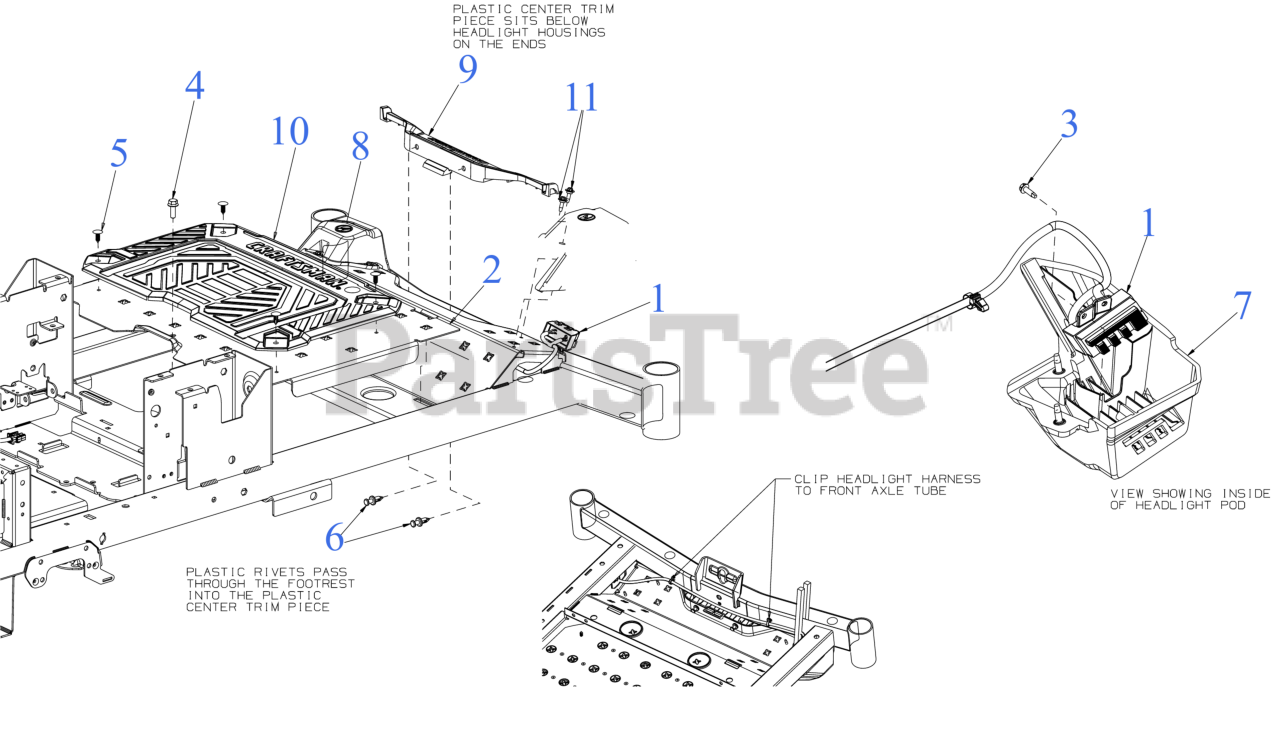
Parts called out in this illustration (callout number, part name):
1	HEADLIGHT HARNESS
2	FLOORBOARD
3	SCREW #8-16 x .50
4	SCREW 5/16-18 x .875 GR5 HXFLG HD
5	RATCHET CLIP .250
6	PLASTIC RIVET
7	HEADLIGHT COVER (RH)
8	HEADLIGHT COVER (LH)
9	HEADLIGHT COVER (CENTER)
10	FLOORBOARD MAT
11	SHOULDER SCREW M6-1 .368 X.115
